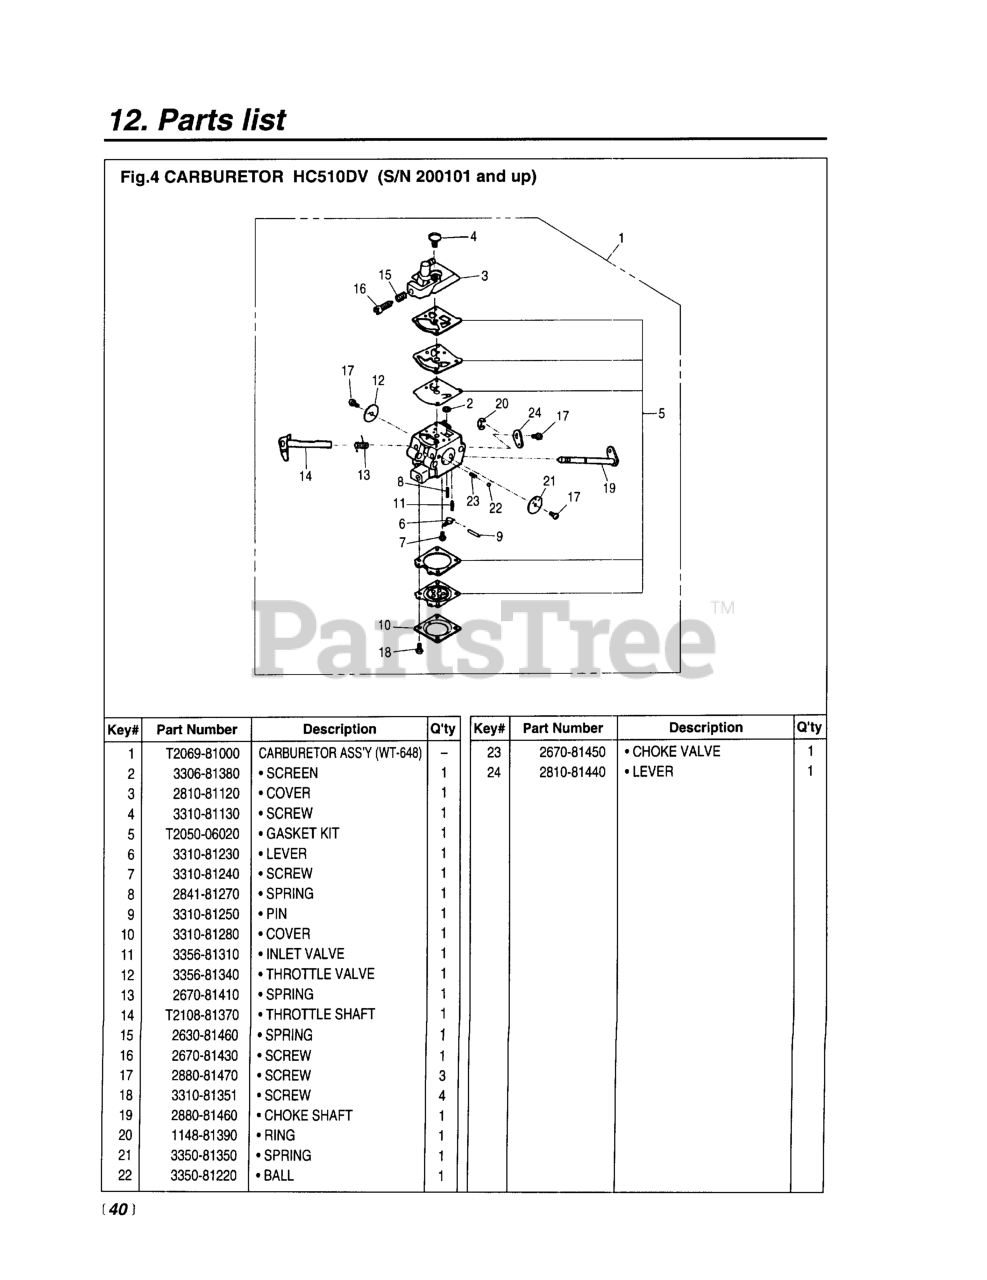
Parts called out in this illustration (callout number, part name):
1	CARBURETOR ASSY. (HC510DV)
3	COVER ASSEMBLY
5	GASKET KIT
6	LEVER
8	SPRING (USE 2867-81270)
9	PIN, METERING LEVER
11	VALVE, INLET
12	VALVE, THROTTLE
13	SPRING, RETURN
14	SHAFT ASSEMBLY, THROTTLE
15	SPRING, IDLE
17	SCREW (RPLS 3310-81360)
18	SCREW ASSEMBLY
19	SHAFT, CHOKE
21	SPRING
22	BALL, FRICTION
23	VALVE, CHOKE
